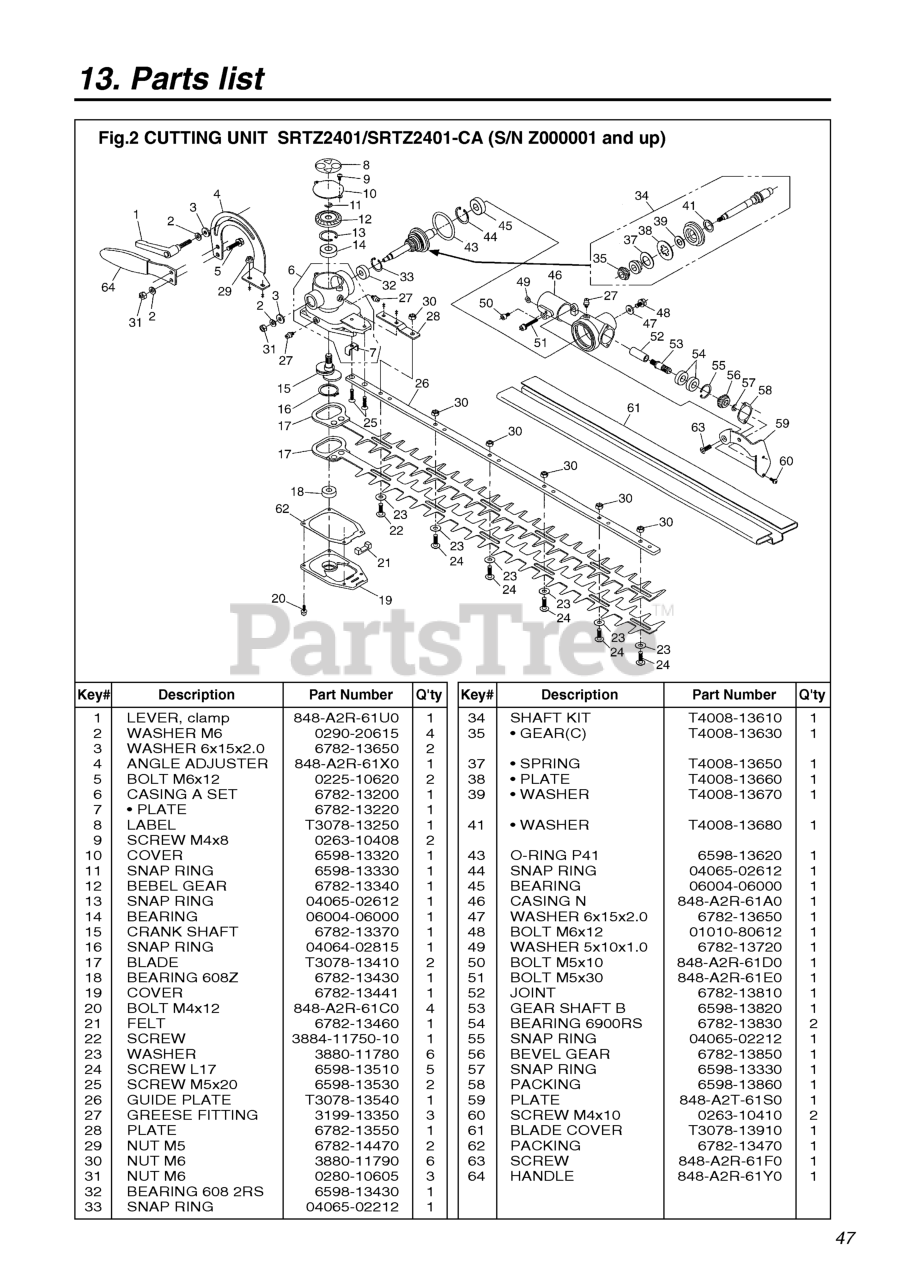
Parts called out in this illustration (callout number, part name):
1	LEVER, CLAMP
2	WASHER M6
3	WASHER, 6X15X2.0
4	ANGLE ADJUSTER
5	BOLT M6X12
6	CASING A SET
7	PLATE
8	LABEL
9	SCREW, M4 X 8
11	SNAP RING
12	BEVEL GEAR
13	SNAP RING
14	BEARING
15	CRANKSHAFT
16	SNAP RING
17	BLADE
18	BEARING
19	COVER
20	BOLT M4X12
21	FELT
23	WASHER
24	SCREW
25	SCREW
26	GUIDE PLATE
27	GREASE FITTING
28	PLATE
29	NUT, M5
30	NUT
31	NUT M6
32	BEARING
33	SNAP RING
34	SHAFT KIT
35	GEAR (C)
37	SPRING
38	PLATE
39	WASHER
41	WASHER
43	O-RING
44	SNAP RING
45	BEARING
46	CASING N
47	WASHER, 6X15X2.0
48	BOLT M6X12
49	WASHER 5X10X1.0
50	BOLT M5X10
51	BOLT M5X30
52	JOINT
53	GEAR SHAFT B
54	BEARING
55	SNAP RING
56	BEVEL GEAR
57	SNAP RING
58	PACKING
59	PLATE
60	SCREW, M4 X 10
61	BLADE COVER
62	PACKING
63	SCREW
64	HANDLE
